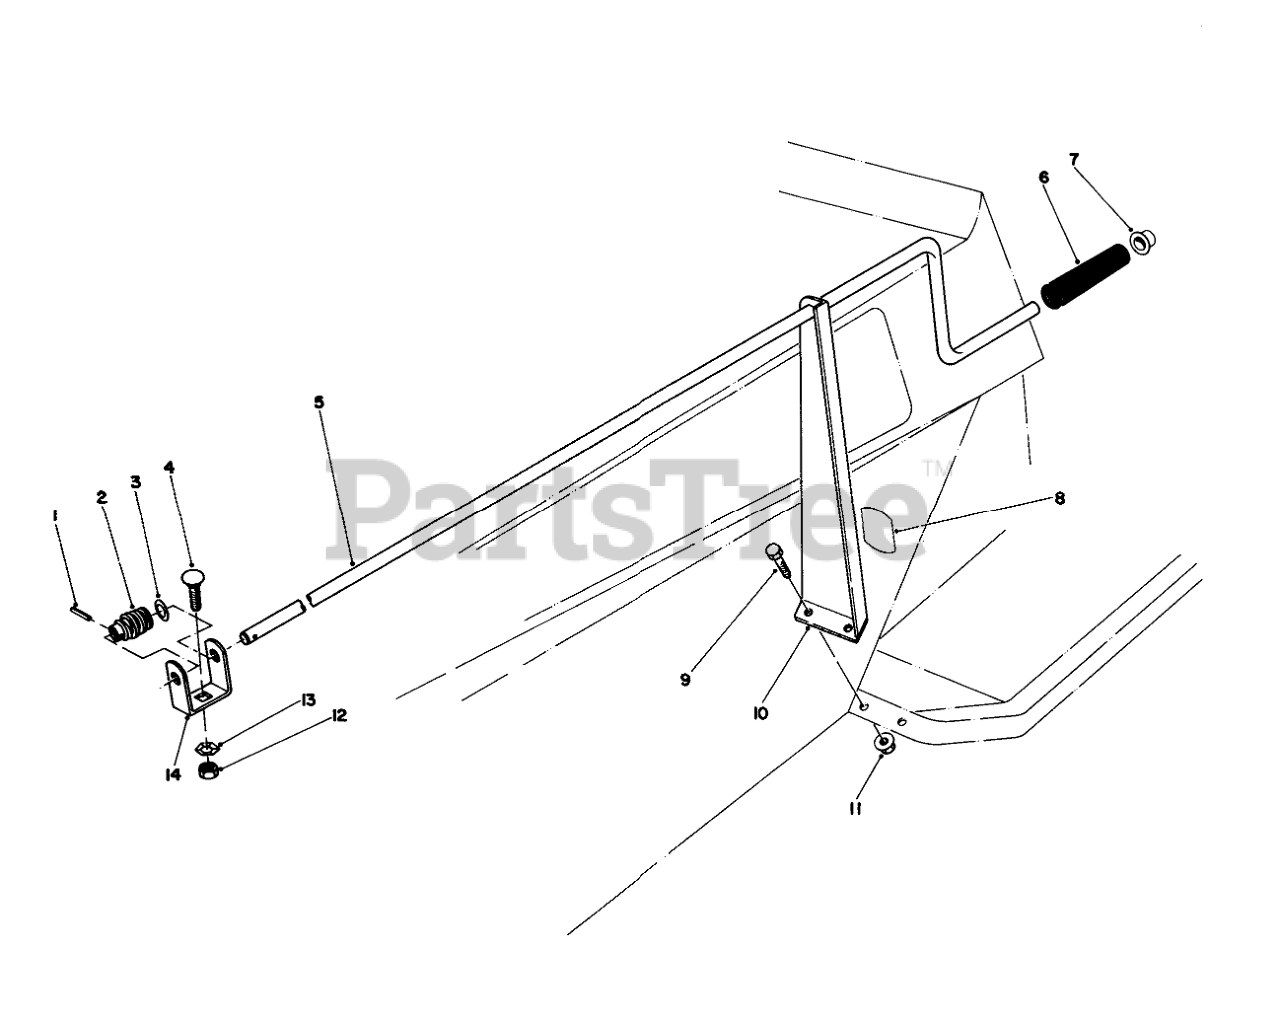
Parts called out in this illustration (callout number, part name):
1	PIN-SPRING
2	GEAR-WORM, CHUTE
3	WASHER-SPRING
4	BOLT-CARR
5	ROD-CHUTE CONTROL
6	GRIP-CONTROL, CHUTE
7	RETAINER-PUSH ON
8	CHUTE DECAL
9	SCREW-HH
10	CHUTE CONT BRKT B
11	NUT-HF
12	NUT-LOCK, NI
13	WASHER-LOCK
14	WORM BRKT B
